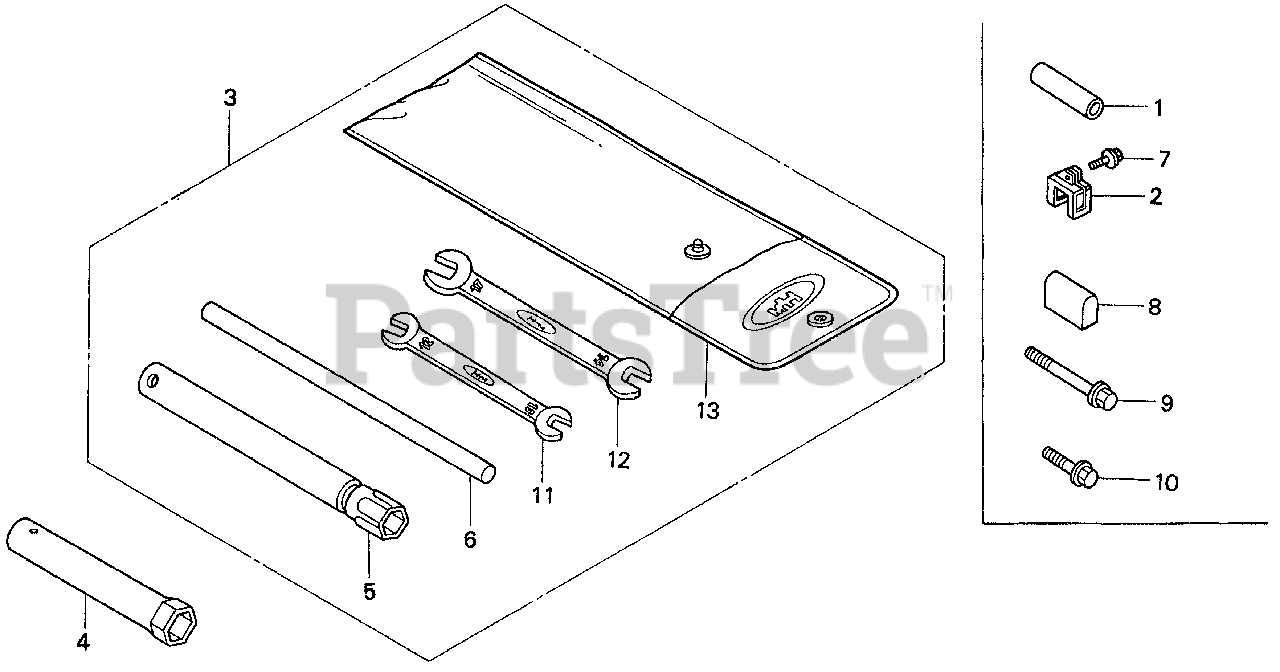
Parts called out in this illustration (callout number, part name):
3	TOOL KIT
5	WRENCH, SPARK PLUG
6	HANDLE, BOX WRENCH
11	WRENCH (10X12) (OPEN END)
12	WRENCH (14X17) (OPEN END)
13	BAG, TOOL (230MM)
